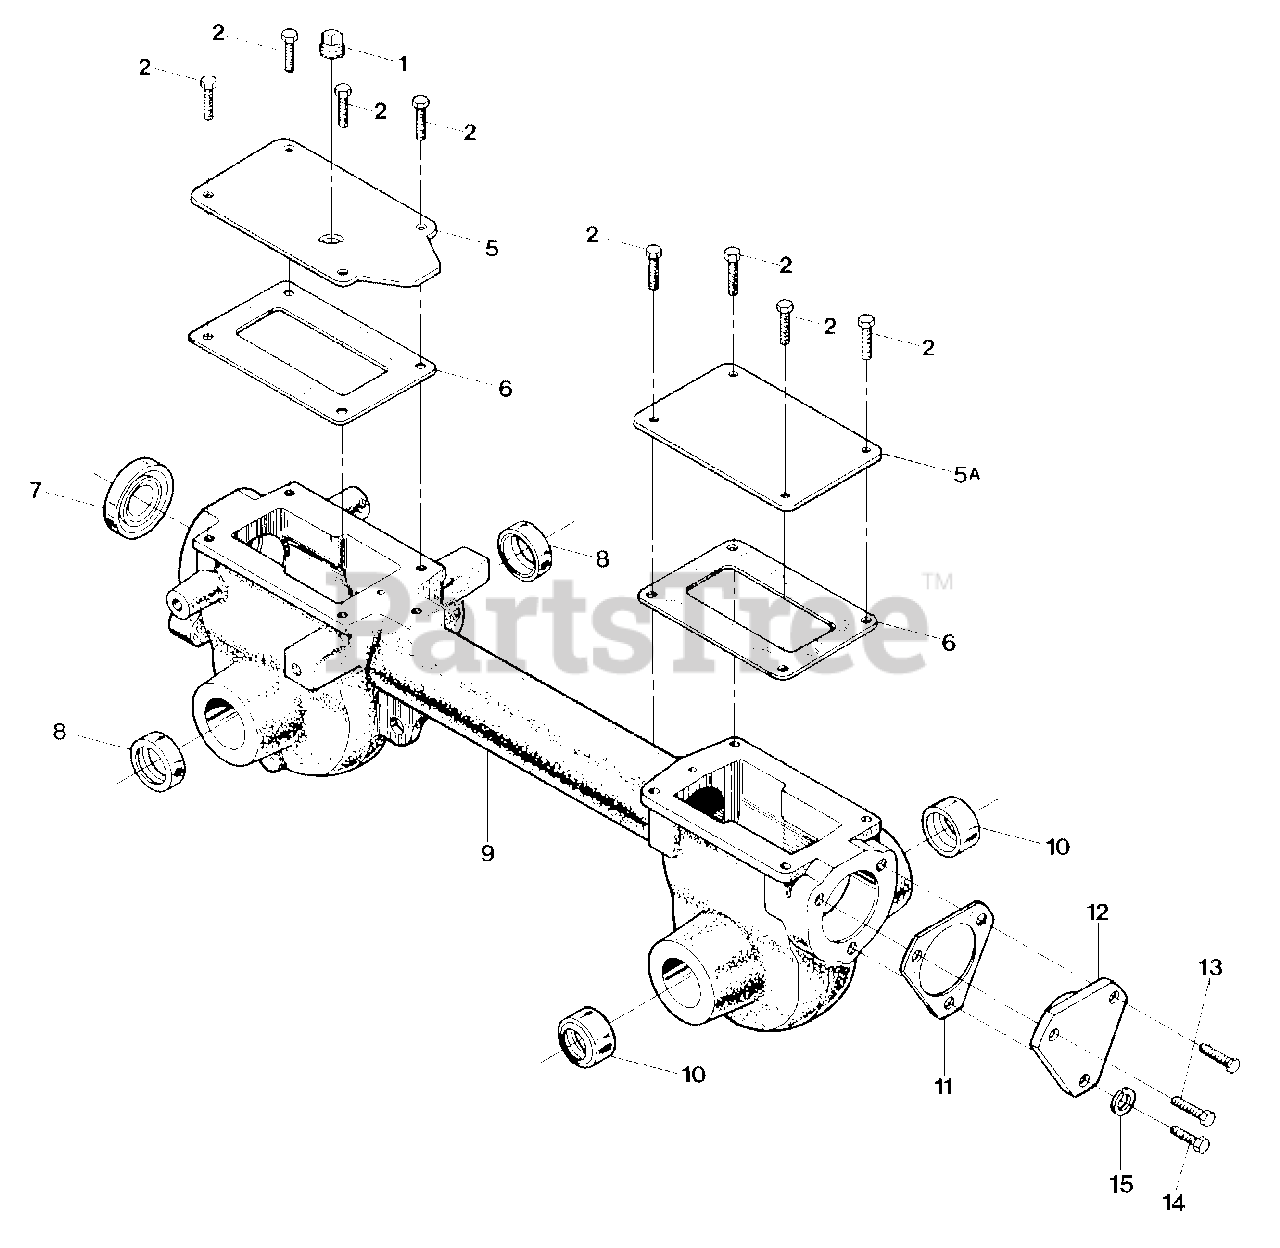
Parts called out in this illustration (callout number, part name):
1	Plug, Transmission Oil Fill
2	Hex Hd. Flange Screw, 5/16-18 x 5/8, Grade 5
5	Front Cover, Transmission
5A	Rear Cover, Transmission
6	Gasket, Housing Cover
7	Oil Seal, Drive Shaft
8	Oil Seal, Wheel Shaft
9	Transmission Housing Ass'y
10	Oil Seal, Tine Shaft
11	Bearing Cap Gasket, .010" thick
12	Rear Bearing Cap
13	Hex Hd. Flange Screw, 5/16-18 x 1
14	Hex Hd. Flange Screw, 5/16-18 x 3/4
15	Lock Washer, 5/16
